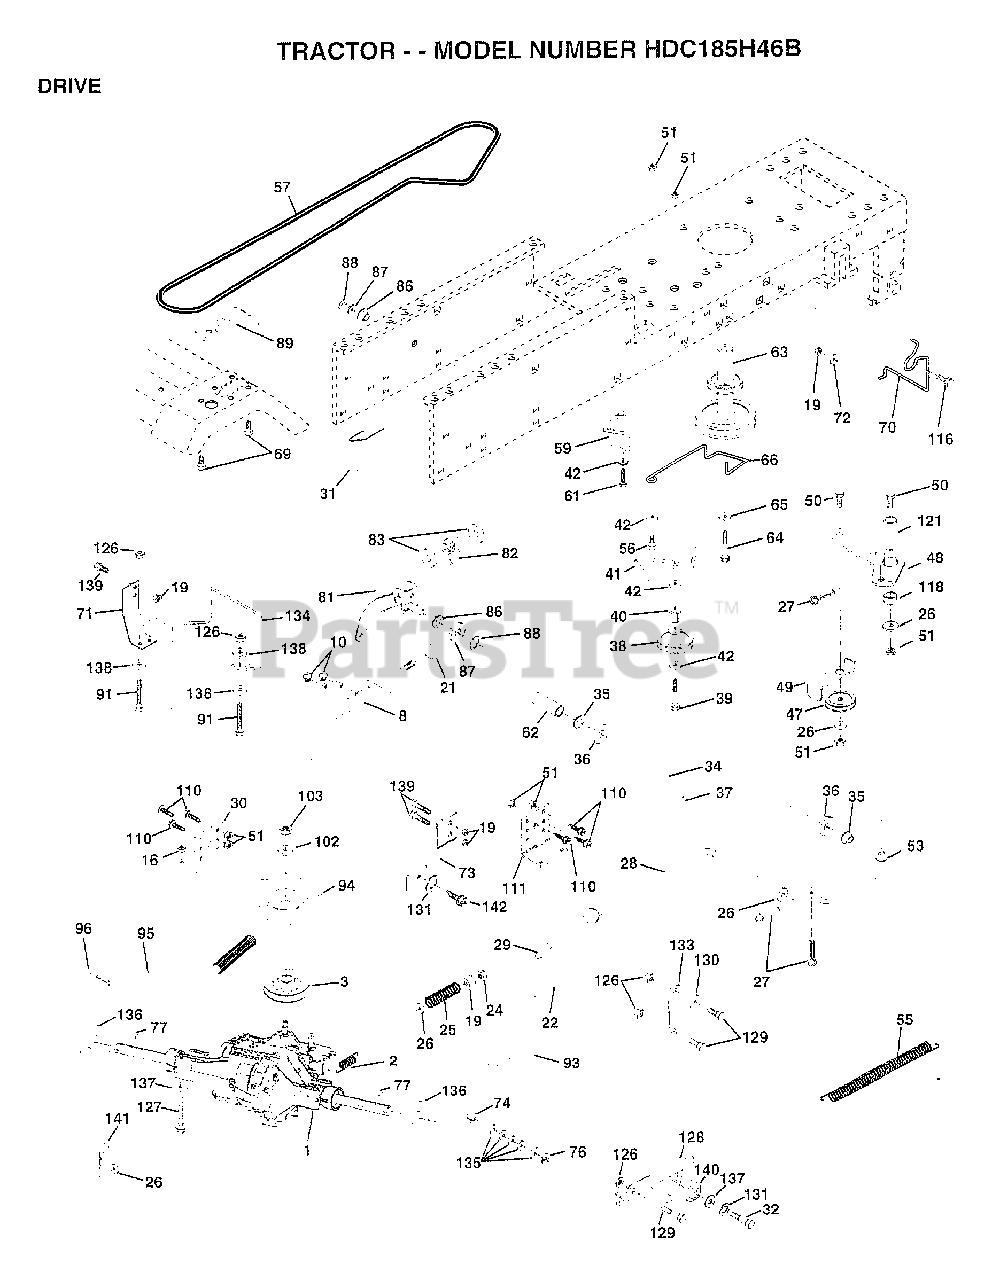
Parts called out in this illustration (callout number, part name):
2	SPRING RET BRAKE
3	PULLEY.TRANSAXLE
8	ROD SHIFT FEND YT
10	PIN COTTER 1/8
16	NUT
19	NUT
21	KNOB T (1/2-HOLE)
22	BRAKE.ROD.HYDRO.
24	NUT
25	SPRING ROD LT
26	WASHER
27	COTTER PIN
28	ROD.BRAKE.PARK.LT
29	PLUNGER CAP T
30	BRKT TRANS LH
31	KEEPER BELT LH
32	BOLT
34	SHAFT ASM-PEDAL F
35	NYLON BEARING
36	WASHER LT
38	PULLEY.IDLER.FLAT
39	BOLT
40	SPACER T
42	WASHER
48	BELLCRANK ASM
49	RETAIN BELT
53	"LINK, CLUTCH T"
55	"SPRING, RETURN LT"
57	BELT.V.PRI.44.V
59	KEEPER BELT CNTSP
62	PEDAL COVER T
63	PULLEY.ENGINE
64	BOLT
65	LOCKWASHER
66	KEEPER-BELT
69	SCREW HEXWSH H-L
70	"GUIDE.BELT,RH ENG"
71	STRAP.TORQUE.LH.HYDRO
72	WASHER
73	STRAP.TORQUE.RH.HYDRO
76	E RING HYT
77	SQ KEY STD
81	SHAFT ASM. CROSS HYDRO 20" TIRES
82	"SPRING,TORSION"
83	WASHER
86	BUSHING
87	WASHER D
88	KLIP RING
93	"LINE FUEL HYD 4"""
94	"FAN 7"" HYDRO"
95	CONTROL.ASM.BYPAS
96	RETAINER M
100	WASHER M
102	WASHER BELLEVILLE
111	BRKT TRANS RH
116	BOLT RDHD 3/8-16
118	SPACER-BELLCRANK
121	NYLINER-CLUTCHING
127	BOLT FIN HEX 5/16
128	BRKT NEUTRAL ADJ
130	WASHER
132	WASHER
133	LINK.SHIFT-HYDRO
134	"KEEPER BELT,RH"
135	WASHER
136	WASHER AXLE HYDRO
137	WASHER
138	WASHER
139	BOLT
140	BUSHING.PINION.SECTOR
142	BOLT.5/16X24X1
